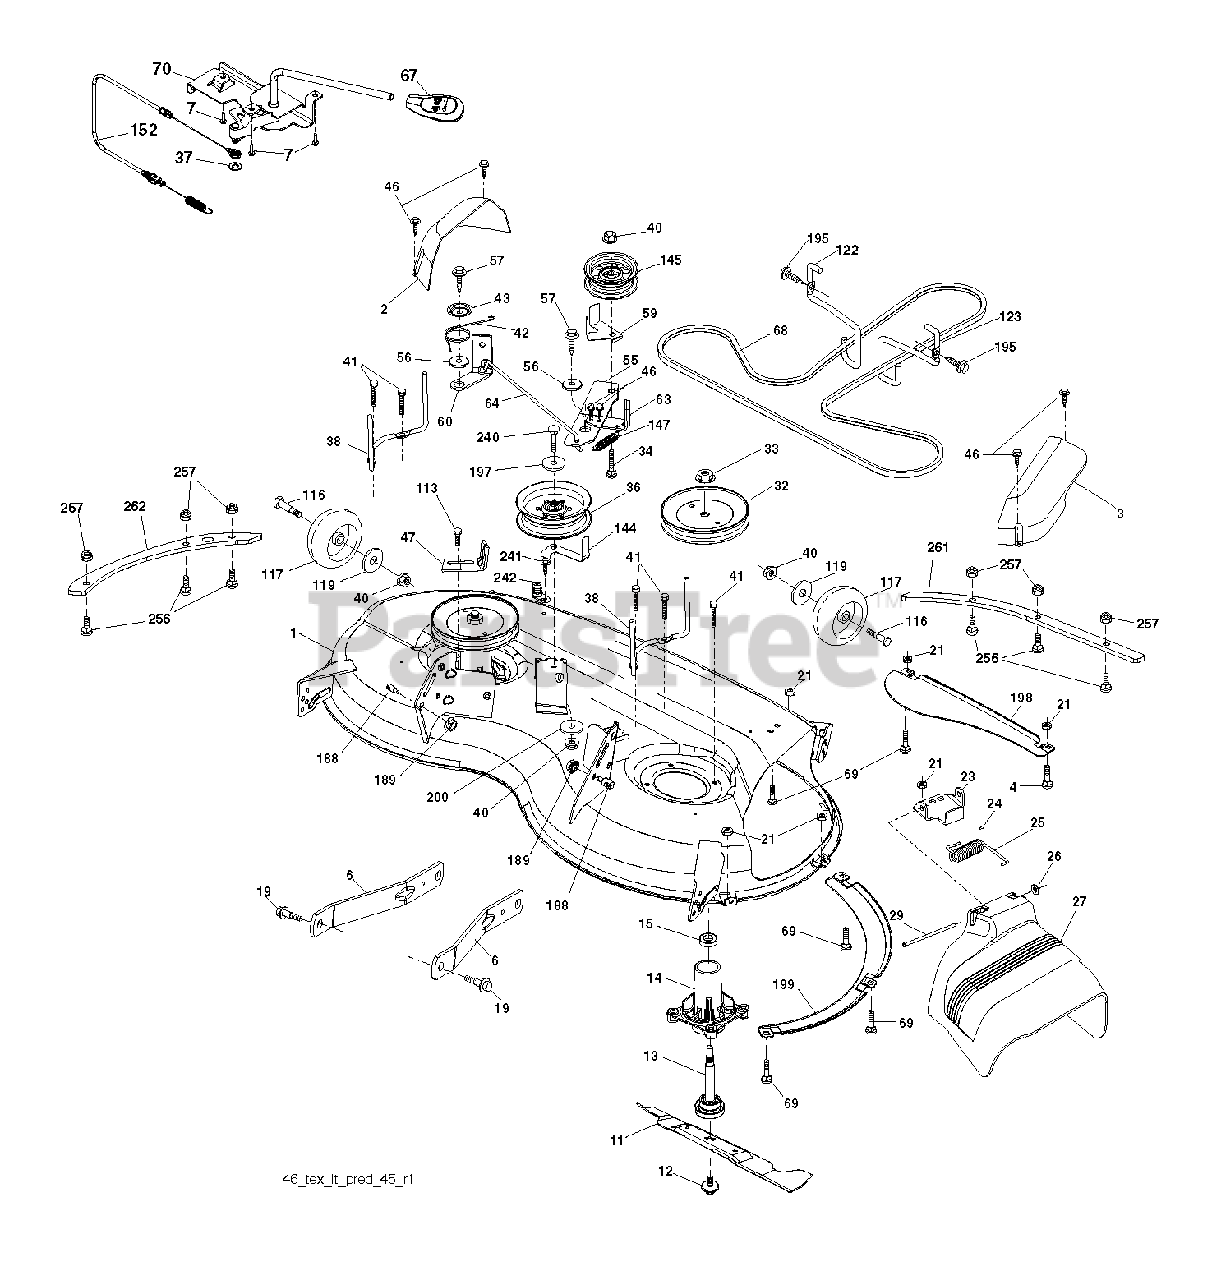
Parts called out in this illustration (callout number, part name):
1	DECK SVC 46"583900906X421
2	COVER.MANDREL.LH.46"
3	COVER.MANDREL.RH.46"
4	BOLT
6	ARM.SUSPENSION.MOWER.R
7	SCREW.#10 X 0.750.BOS (2 2)
11	BLADE.MOWER.46".HI.LIFT
12	Screw, 7/16 X 20 X 1"
13	SHAFT.ASM.MDRL.N/GREASE.38
14	HOUSING.MANDREL.4PT.
19	BOLT.SHOULDER
21	LOCKNUT
23	BRKT.DEFLECTOR.38"2005+
24	CAP-SLEEVE LT
25	SPRING.TORSION.DEFLECT
26	NUT PUSH M
27	SHIELD.DEFLECTOR.MOWER.46"BLAC
29	ROD.HINGE
32	PULLEY.MANDREL.5.438.PD
33	NUT.FLANGE.LOCK.TOP
34	BOLT.3/8-16X1.50
36	PULLEY.IDLER.2006
38	KEEPER.BELT.MANDREL.PULLEY
40	NUT LOCK FLG 3/8-16 UNC
41	Hex Washer Head Bolt, .313-18 X 1.19
42	SPRING.TORSION.BRAKE
43	SRPING.TORSION.RETAINE
46	SCREW.1/4-20X5/8
47	BRKT.CLUTCH.CABLE
55	IDLER.ARM
56	SPACER.RETAINER
57	SCREW 3/8-16X1
59	GUARD, BELT
60	ARM BRAKE MOWER RH 38"
64	LINKAGE BRAKE
67	HANDLE.CLUTCH.CABLE.LT
68	V-BELT
69	BOLT
70	CLUTCH.ASM.MANUAL.YT.PREDATORQ
113	BOLT.5/16HEX.WHS.HD
116	BOLT M
117	WHEEL.GAGE.HALF.SPOKED
119	WASHER
122	KEEPER BELT ENGINE LH
123	KEEPER BELT RH
144	KEEPER.BELT.MOWER
145	PULLEY.IDLER.48"PRIMARY
147	SPRING RETURN
152	CABLE.MECHANICAL.CLUTCH
188	STUD.FASTNER.W/ANTI-ROTATE
189	NUT LOCK HEX FLANGE 5/16-18
195	SCREW, 3/8-16X3/4
197	WASHER
198	BAFFLE CENTER FRONT
199	BAFFLE FRONT RH
200	WASHER.13/32 X 1 X 1/2.11GUARD
240	BOLT-HEX EAK
241	SCREW.TT.#10-32X.5.3/8.FLANGE
242	PORT.WASHOUT
256	Buttonhead Screw, 5/16-18
257	NUT T
261	Deck Reinforcement Plate, 46 F
262	Side Reinforcement Plate, 46" Bolt-on
